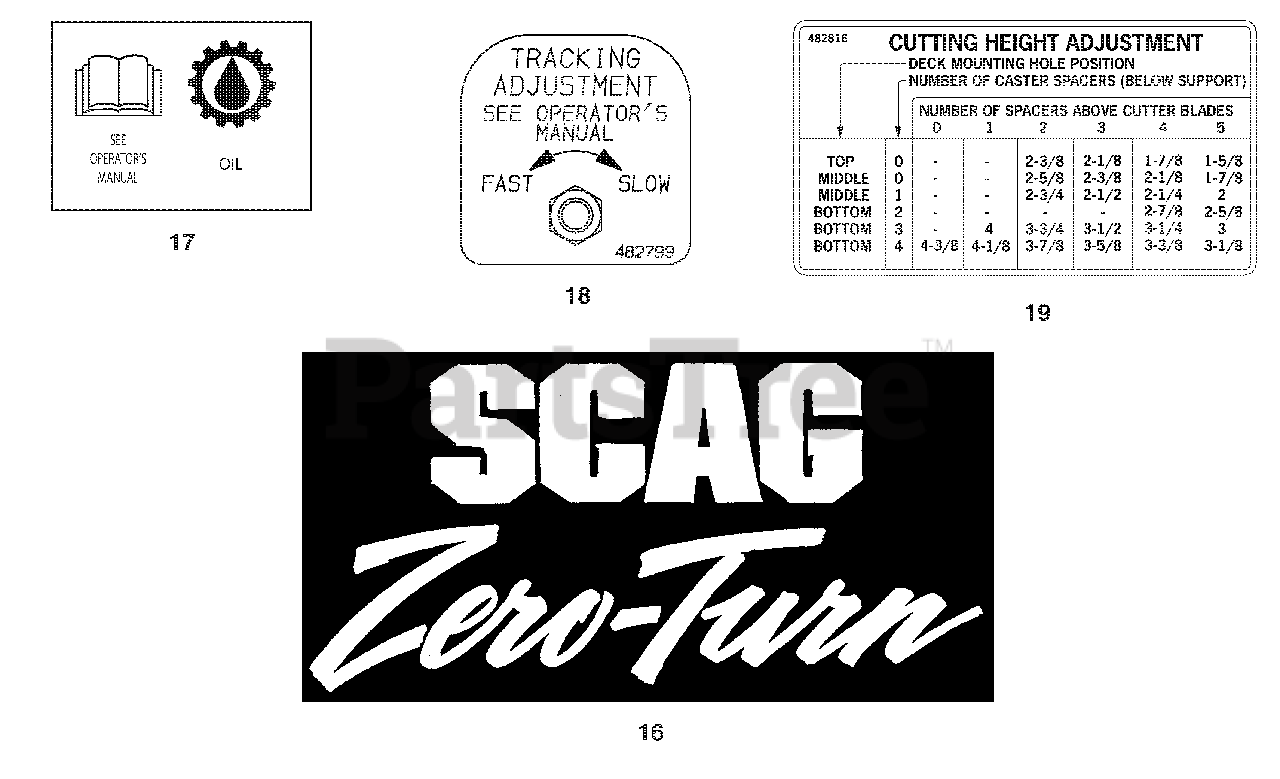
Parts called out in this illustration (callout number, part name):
16	Decal, Scag Zero Turn
17	Decal, Oil
18	Decal, Tracking Adjustment
19	Decal, Height of Cut
